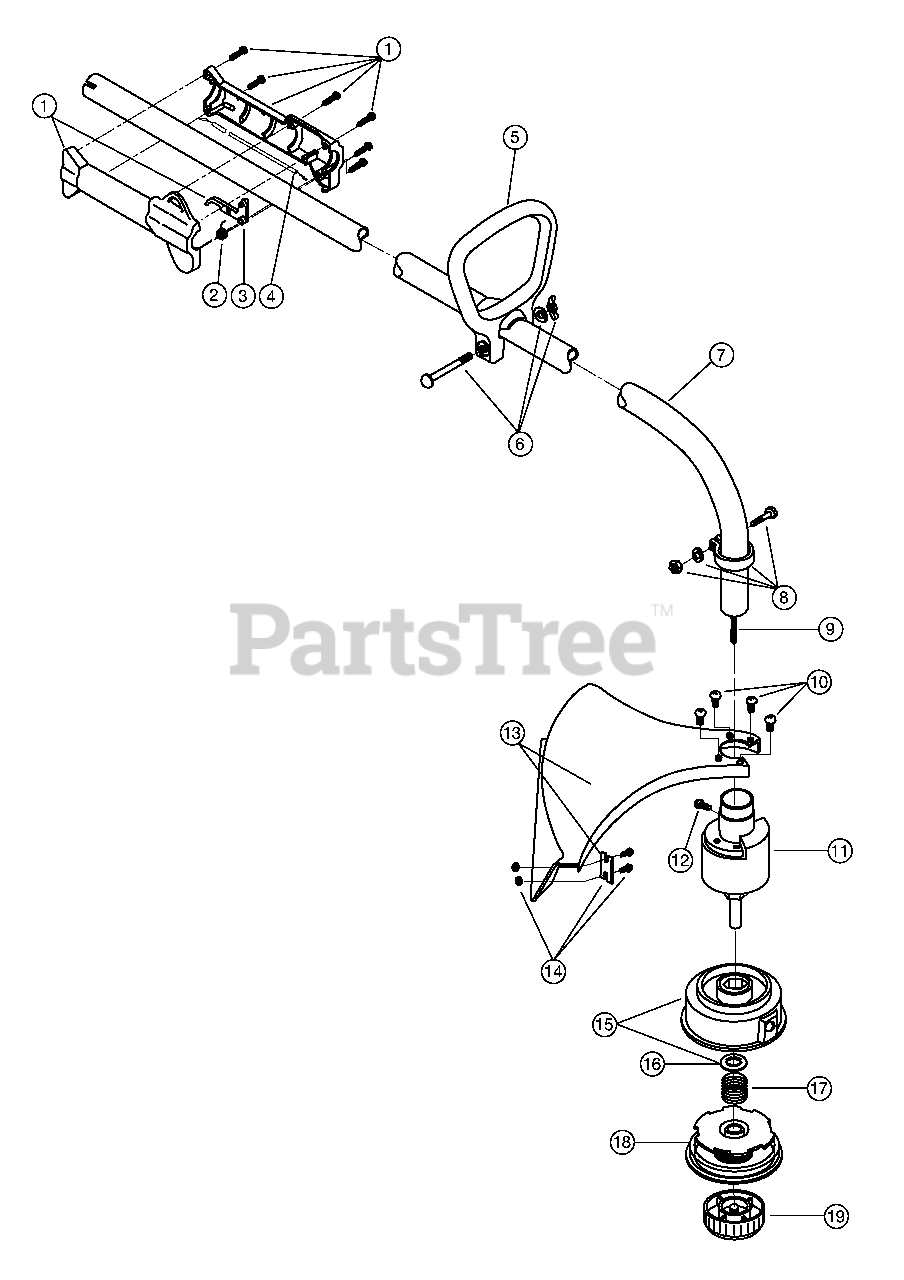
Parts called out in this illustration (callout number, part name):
1	Throttle Housing and Trigger Assembly
2	Throttle Trigger Spring
3	Throttle Trigger
4	Throttle Cable Assembly
5	D-Handle Assembly
6	D-Handle Hardware
7	Drive Shaft Housing Assembly
8	Lower Clamp Assembly
9	Flexible Drive Shaft
10	Shield Mounting Screw
11	Bushing Housing Assembly with Spool Shaft
12	Anti-Rotation Screw
13	Shield and Blade Assembly
14	Blade Assembly
15	Outer Spool and Eyelet Assembly
16	Retainer
18	Inner Reel
19	Bump Head Knob Assembly
